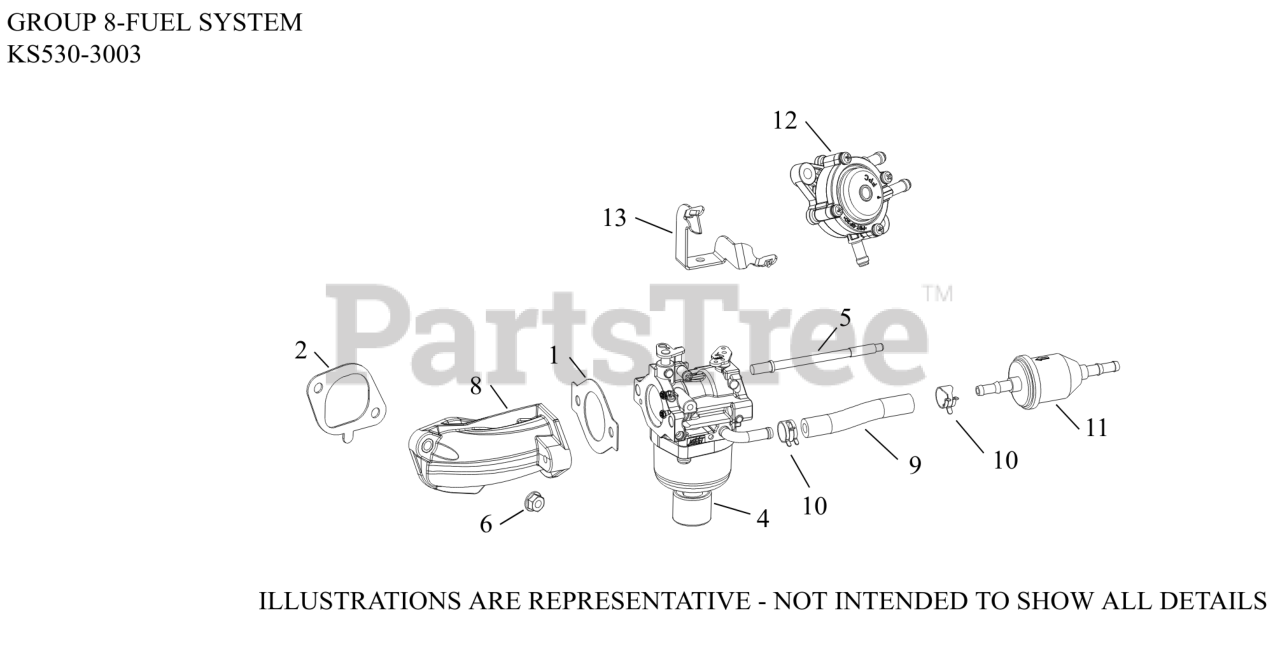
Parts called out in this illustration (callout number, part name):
1	GASKET, CARBURETOR (THROTTLE)
2	GASKET, INTAKE MANIFOLD
4	KIT,CARB(NIKKI)
5	STUD, CARBURETOR
6	NUT, FLG M6X1.0
8	MANIFOLD, INTAKE ASSEMBLY
9	HOSE,LW PERM.FUEL 24.00"-USE 25 111 81-S
10	SPRING CLAMP, HOSE
11	FILTER,FUEL 51 MICRON (FUEL PUMP)
12	PUMP, FUEL (PULSE)-(#2539326S)
13	BRACKET, FUEL PUMP
NI	HIGH ALTITUDE KIT (5000 FT)
NI	KIT, OVERHAUL
NI	KIT, CHOKE SHAFT
NI	KIT, O-RING
NI	KIT, SOLENOID (NIKKI)
NI	KIT, BOWL WITH O-RINGS
NI	KIT, FLOAT & INLET NEEDLE FOR FUEL PUMP
NI	KIT, THROTTLE SHAFT
